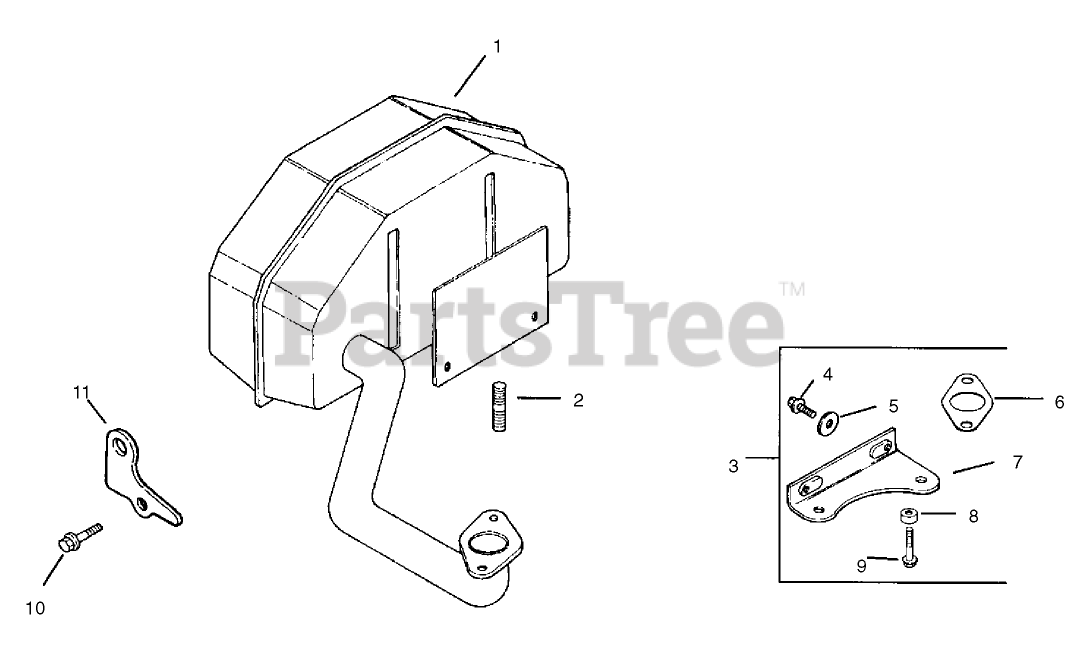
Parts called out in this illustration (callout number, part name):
1	Muffler
2	Stud
3	Kit-Bracket (Incl. Ref.#4-9)
4	Screw
5	Washer
6	Gasket-Exhaust
7	Bracket-Muffler
8	Washer
9	Screw
10	Screw
11	Strap-Lifting
